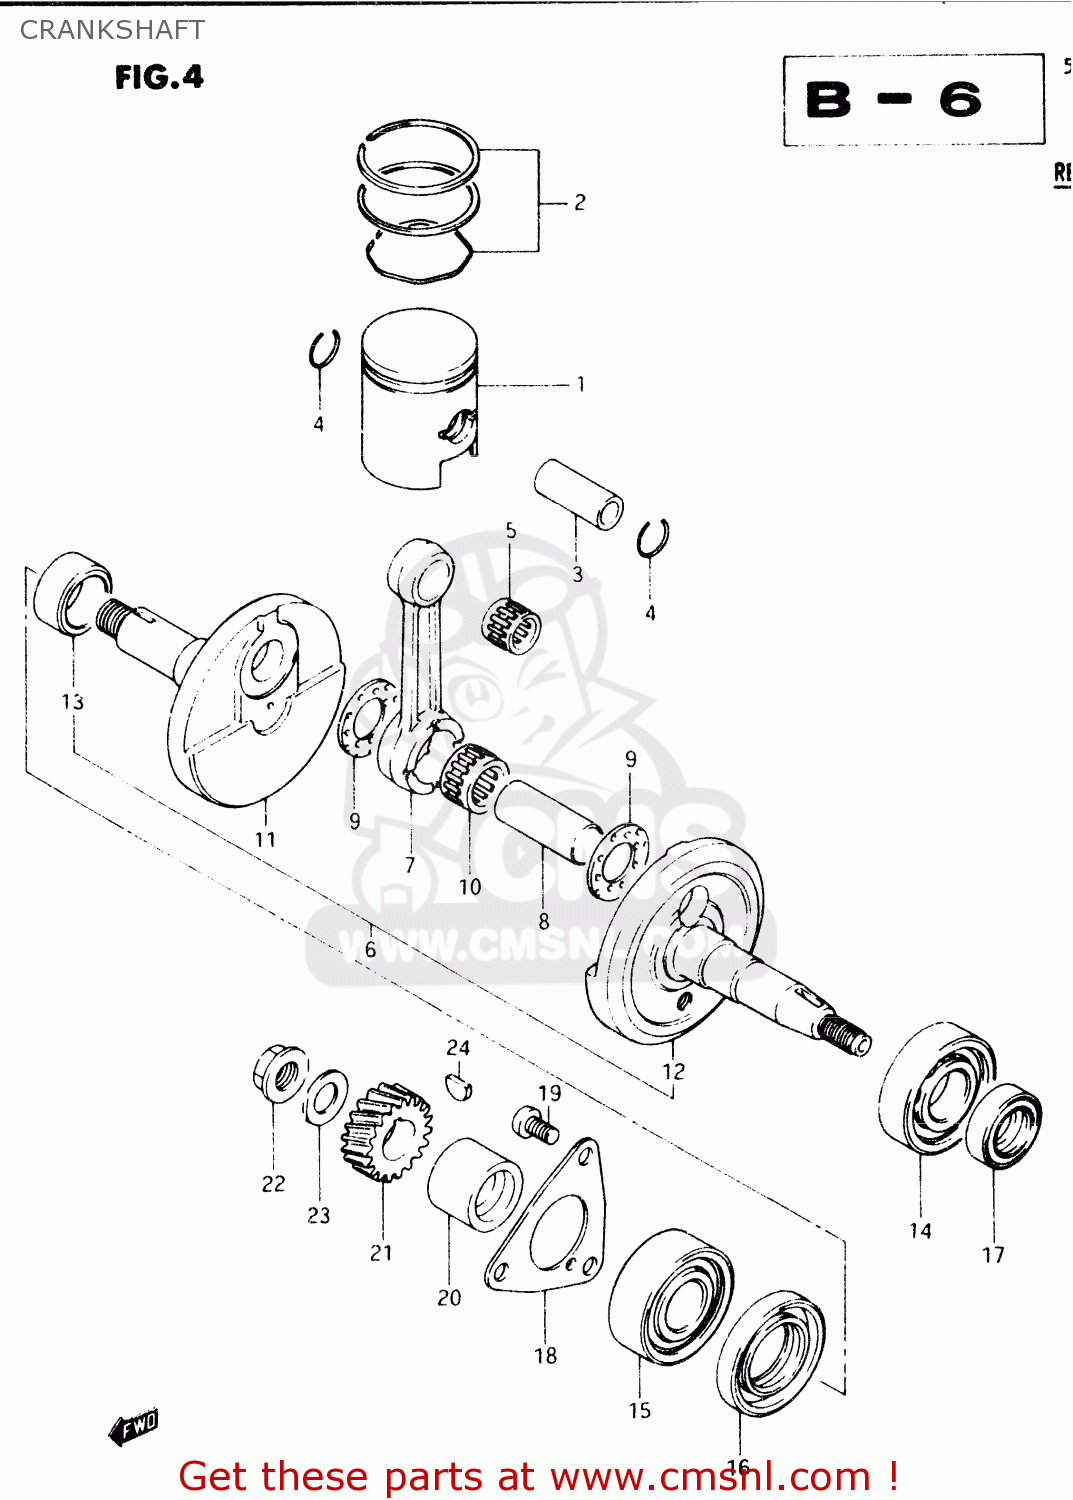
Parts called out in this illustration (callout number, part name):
1	PISTON (41.00MM)
2	RING SET,PISTON
3	PIN,PISTON
4	RING,SNAP
5	ROLLER BEARING (12X16X1
6	CRANKSHAFT
7	ROD,CONNECTING
8	PIN,CRANK
9	WASHER(16X29X1)
10	BEARING
11	CRANKSHAFT, RH
12	CRANKSHAFT,LH
13	SPACER(20X28X10)
14	BEARING(20X47X14)
15	BEARING(20X47X14)
16	SEAL,OIL(28X47X7.3)
17	SEAL,OIL(18X30X8)
18	RETAINER
19	SCREW
20	SPACER
21	GEAR,PRIMARY DRIVE
22	NUT
23	WASHER
24	KEY
